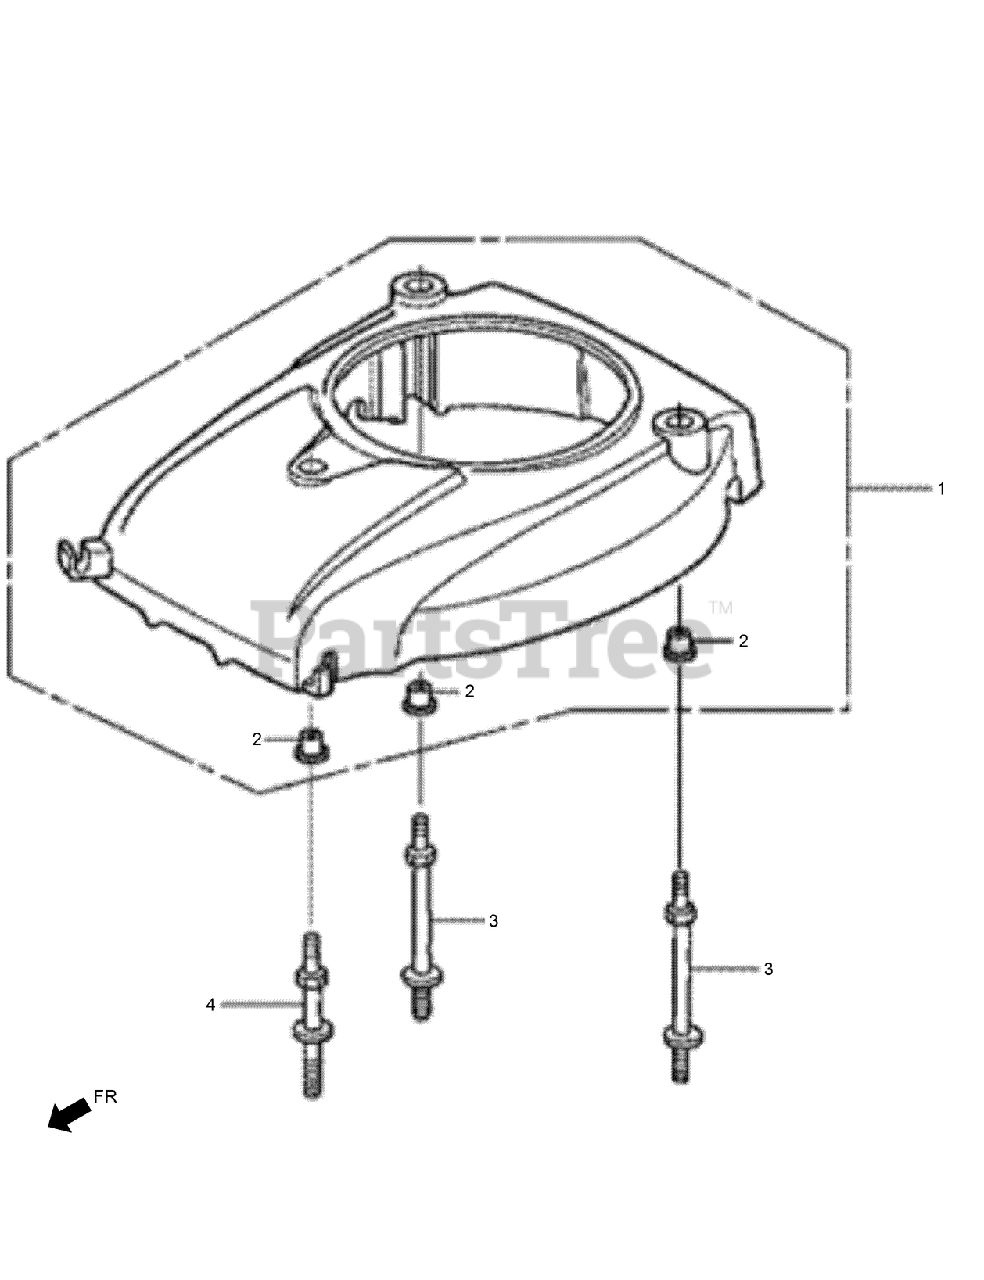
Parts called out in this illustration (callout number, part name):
1	FAN COVER ASM (NH1)
2	COLLAR-FAN COVER
3	BOLT A-STUD
4	BOLT B-STUD
